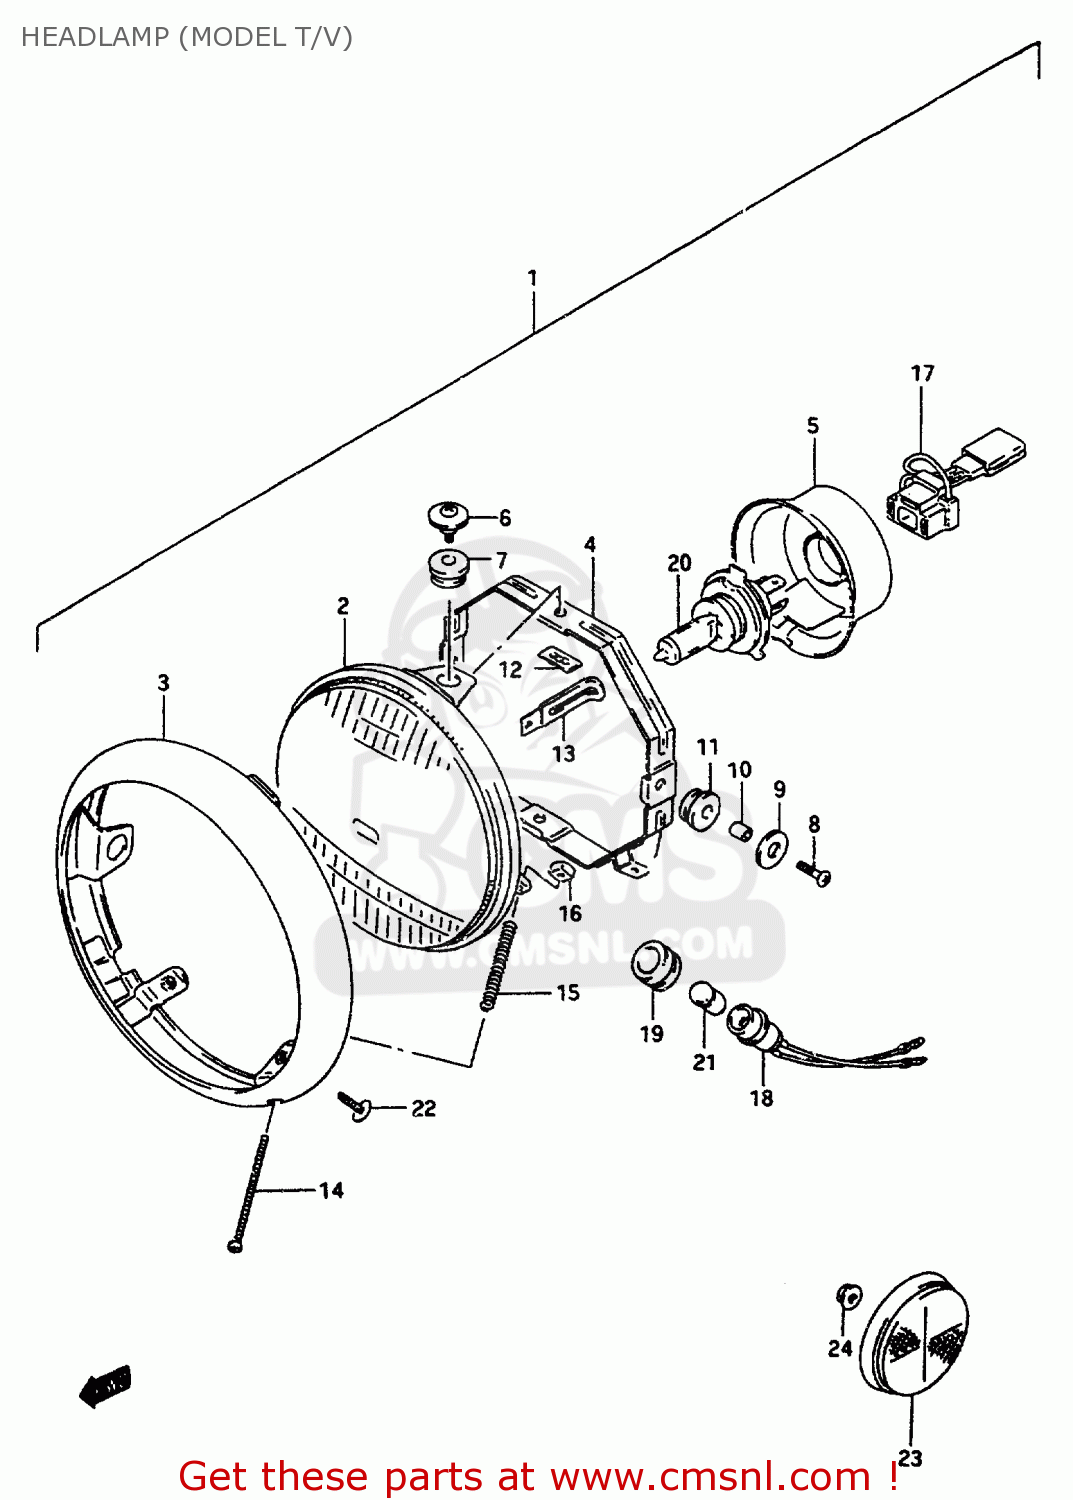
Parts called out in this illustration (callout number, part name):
1	HEADLAMP ASSY
2	UNIT
3	RIM
4	RING,MOUNTING
5	COVER,SOCKET
6	SCREW,MOUNTING
7	CUSHION
8	SCREW
9	WASHER (5.5X18X1)
10	SPACER
11	CUSHION
12	NUT
13	CLAMP(L:45)
14	SCREW,ADJUSTING(4X50)
15	SPRING
16	NUT
17	SOCKET
18	SOCKET
19	JOINT,RUBBER
20	BULB(12V60/55W,H4)
21	BULB(12V3.4W,STANLEY,A72A)
22	SCREW
23	REFLECTOR,REFLEX FR
24	NUT
25	NUT
